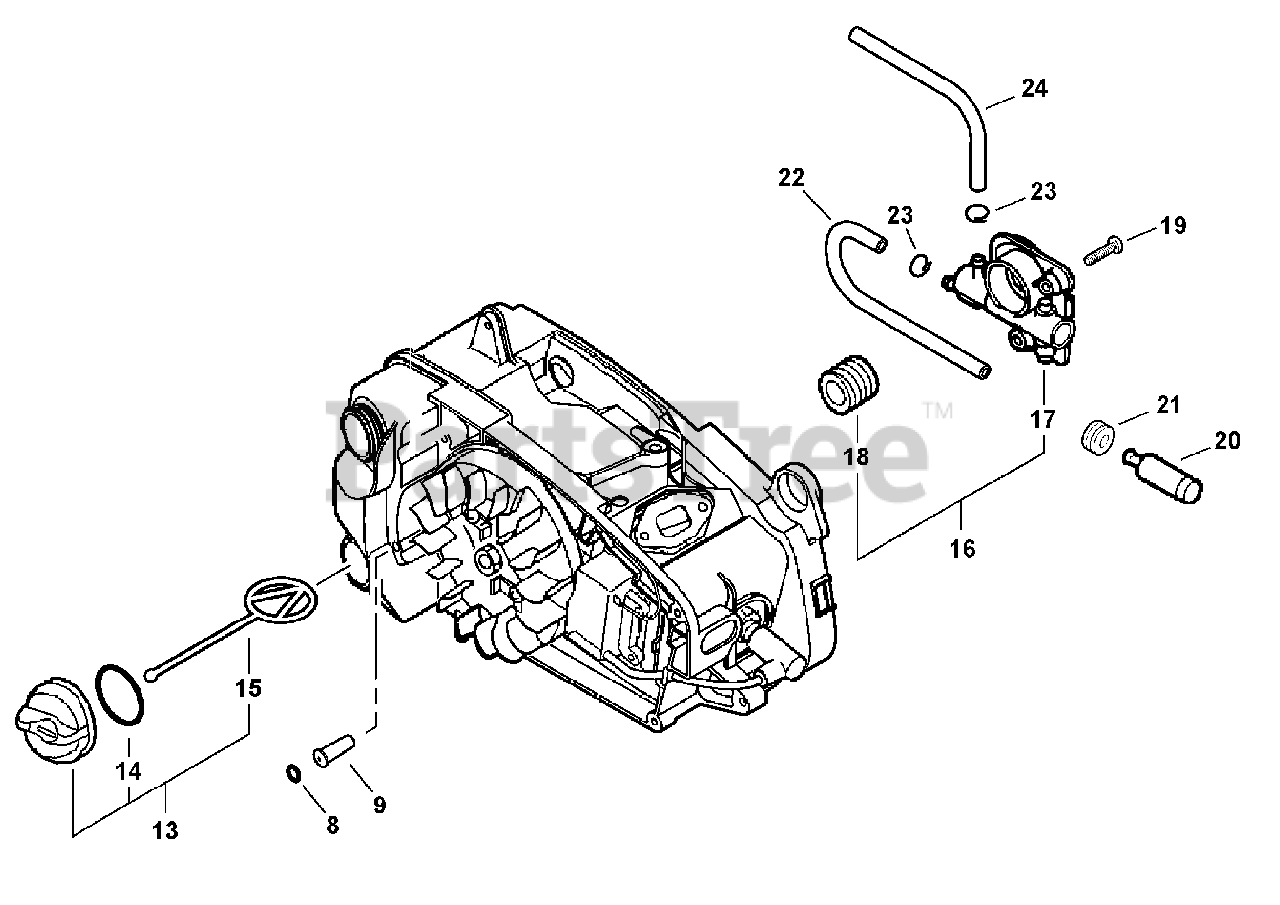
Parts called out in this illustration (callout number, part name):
8	O-RING - 4
9	VENT, TANK
13	CAP ASSY - BLACK
14	O-RING - 18
15	CONNECTOR, CAP
16	AUTO-OILER ASSY
17	AUTO-OILER ASSY
18	GEAR - WORM
19	SCREW - 4X12
20	FILTER, OIL
21	GROMMET
22	PIPE - 3X5X195 -- BLACK
23	CLIP - 6.5
24	PIPE - 3X6X90 -- BLACK
